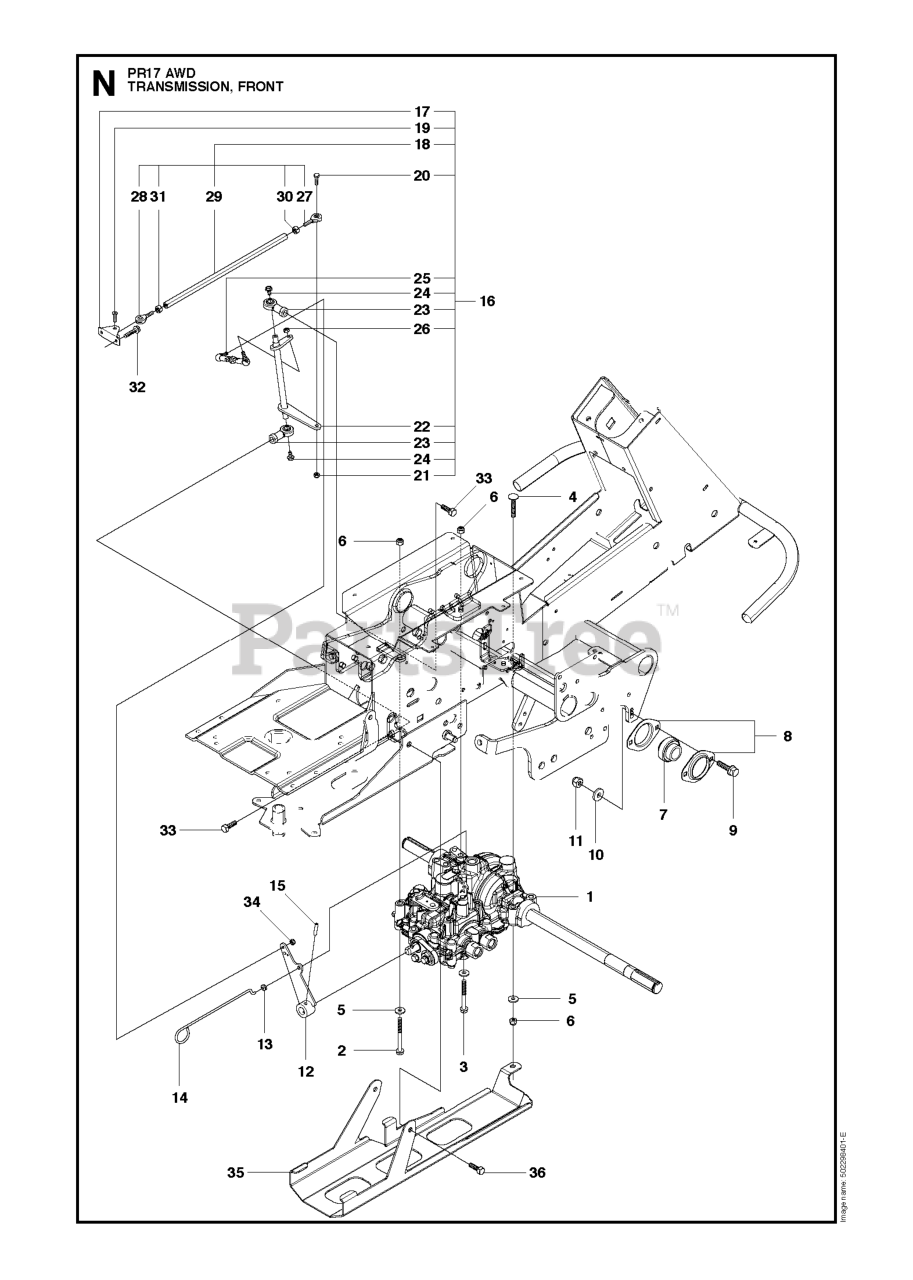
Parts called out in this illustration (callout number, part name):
5	WASHER BRB 8.4X17
6	LOCKNUT M8
8	BEARING HOUSING
9	BOLT
10	WASHER BRB 8.4X17
11	LOCKNUT M8
13	FUEL TANK BUSHING
18	ROD
21	NUT FLANGE - M6
24	SCREW EHHFM
25	ADJUSTING ROD
26	NUT FLANGE - M6
33	Screw M10x25
34	LOCKNUT M6
